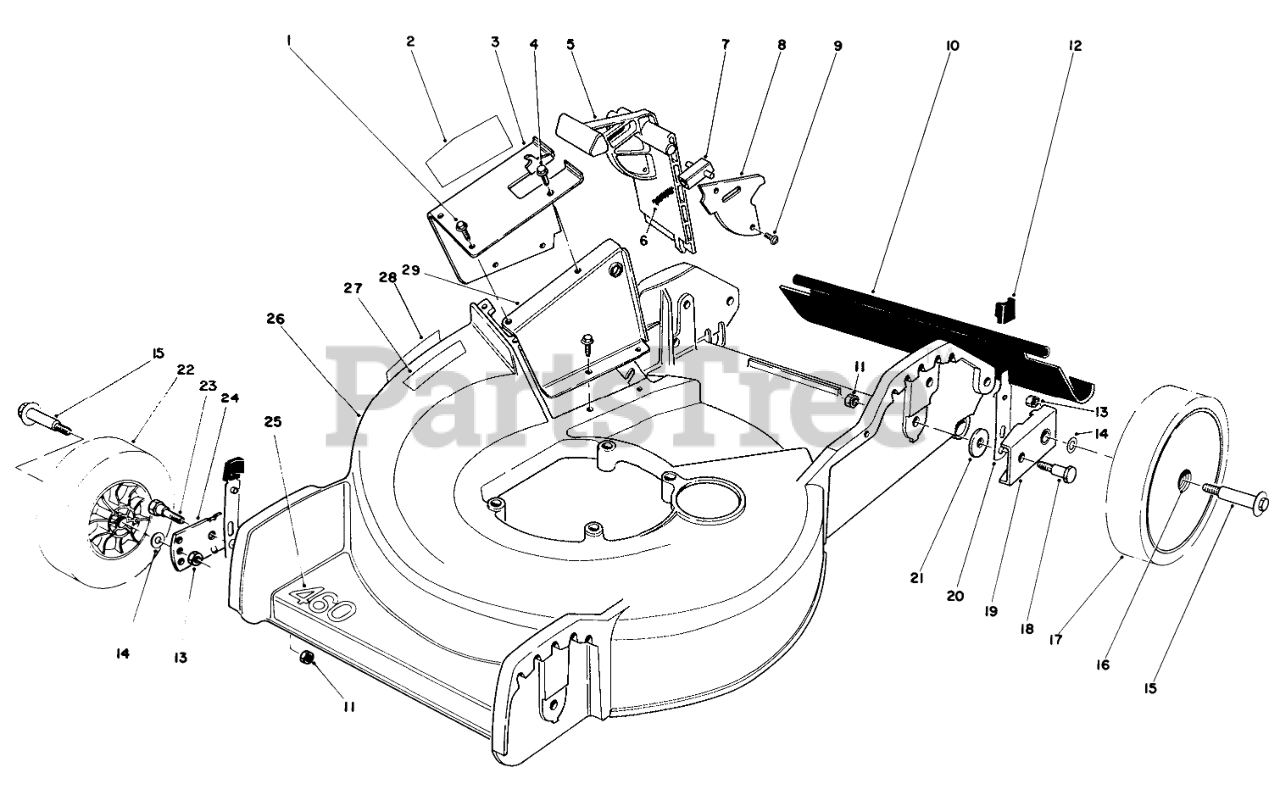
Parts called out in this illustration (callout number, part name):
1	SCREW
2	Decal-Danger
3	Tunnel-Outer (Incl. Ref. #2)
4	SCREW
5	Door Mulching
6	SPRING-COMPRESSION, LATCH
7	Door Latch
8	Cover Door
10	SHIELD - TRAILING
11	NUT-LOCK, NI
12	KNOB-ARM
13	Nut
14	WASHER
15	Bolt-Wheel
16	BUSHING
17	Wheel & Tire Assembly (Incl. Ref. #16)
18	PIVOT SCREW
19	HP PIVOT ARM ASM
20	SPRING ARM ASM
21	PIVOT WASHER
22	Wheel & Tire Assembly (Incl. Ref. #16)
23	PIVOT SCREW
24	PIVOT ARM ASSY
25	Decal-460
26	Housing
27	Decal-Place Foot Here
28	STEP PAD DECAL
29	Tunnel-Inner
